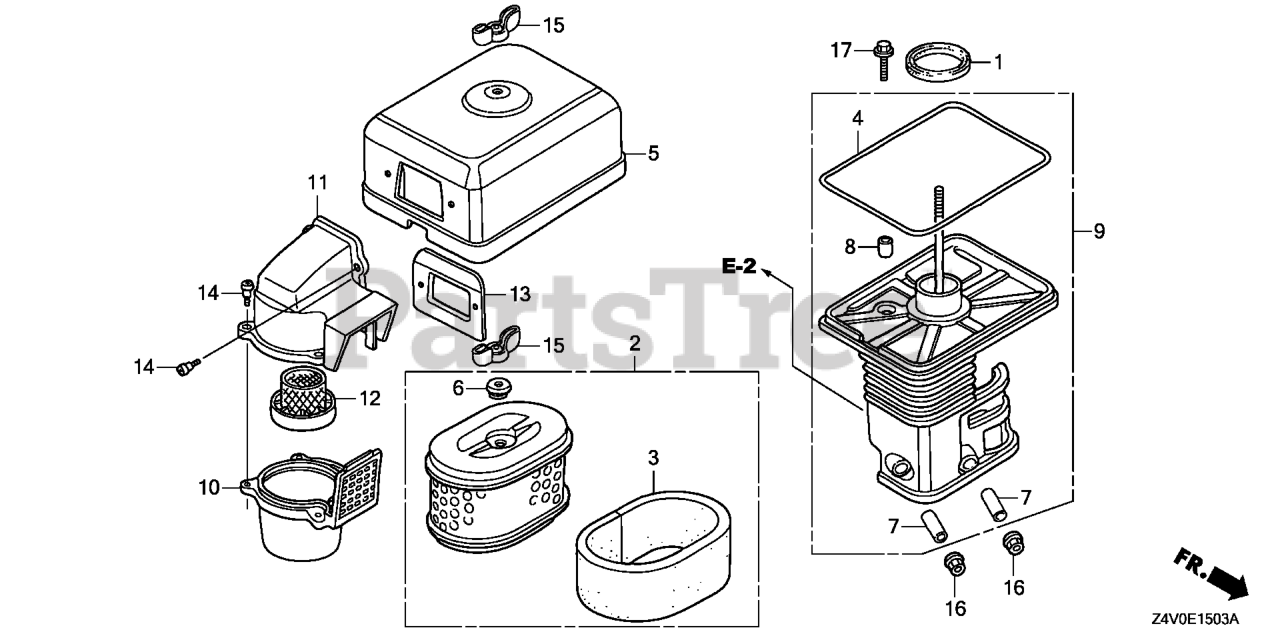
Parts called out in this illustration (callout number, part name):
1	GASKET, ELBOW
2	ELEMENT, AIR CLEANER (DUAL) Use up to Engine SN 2115700.
2	ELEMENT, AIR CLEANER (DUAL)
3	FILTER (OUTER)
4	GASKET, AIR CLEANER COVER
5	COVER, AIR CLEANER (DUAL)
6	GROMMET, AIR CLEANER
7	COLLAR, AIR CLEANER Use from Engine SN 1786085.
8	COLLAR B, AIR CLEANER
9	ELBOW, AIR CLEANER
10	CASE, PRE AIR CLEANER
11	CAP, PRE AIR CLEANER
12	GUIDE, PRE AIR CLEANER
13	PLATE, PRE AIR CLEANER
14	BOLT, MUDGUARD
15	WINGNUT, TOOL BOX SETTING
16	NUT, FLANGE (6MM)
17	BOLT, FLANGE (6X20)
